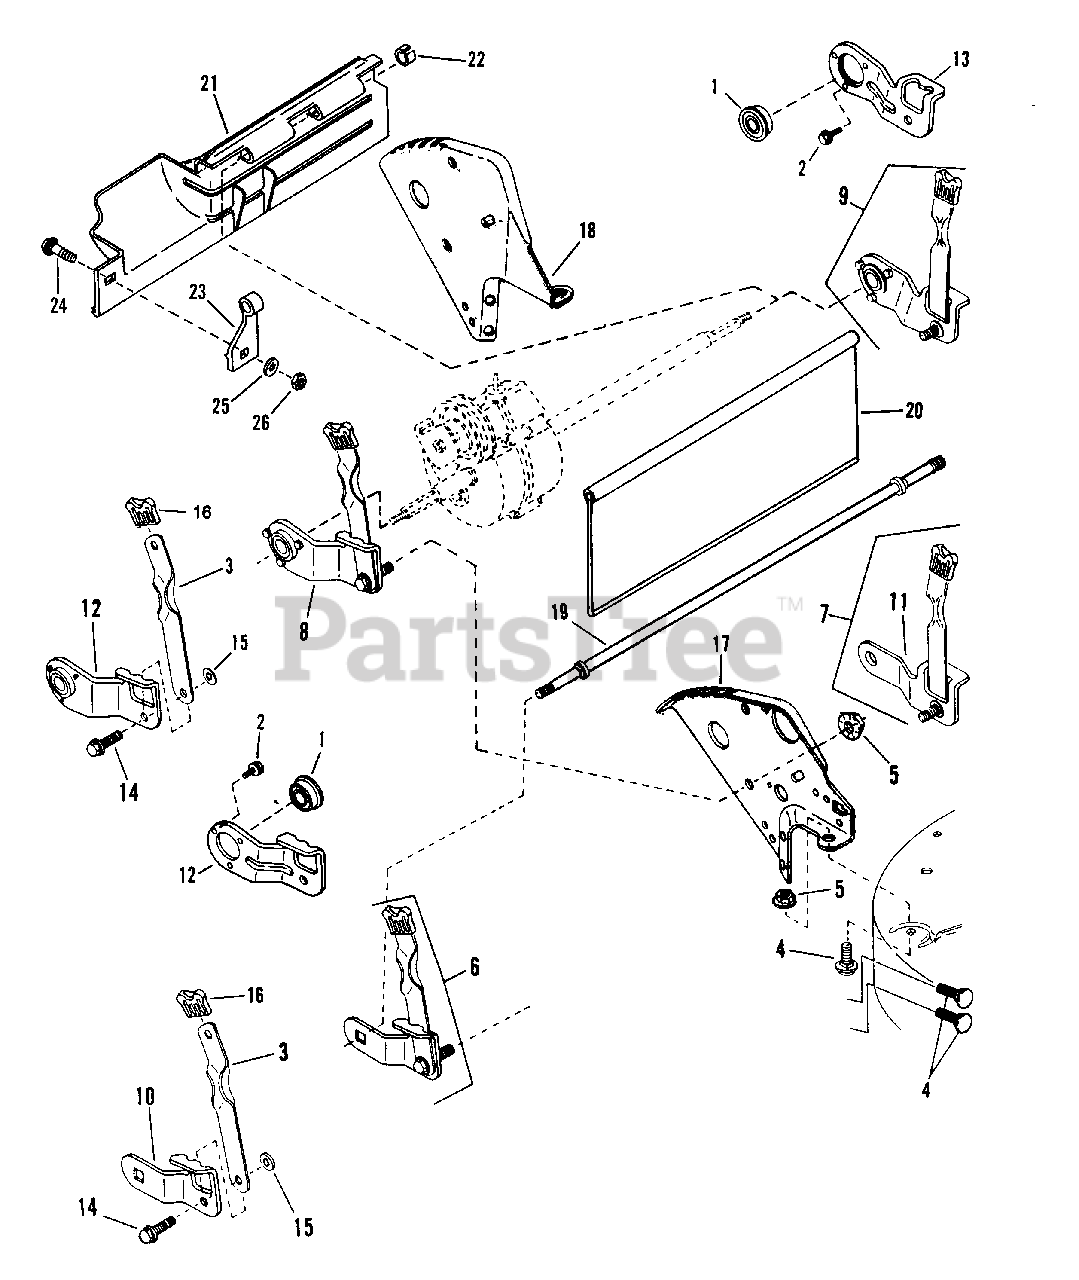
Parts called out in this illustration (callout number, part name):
1	BEARING, 9/16 (Heavy duty)
1	BEARING, 9/16
2	SCREW, #10-32 x 3/8" Self-Tapping (Torx)
3	LATCH, Height Adjusting (Long)
3	LATCH, Height Adjusting - Right (Long)
3	LATCH, Height Adjusting - Left (Long)
4	BOLT, 5/16-18 x 3/4" Short Neck Carriage, Grade 5
5	NUT, 5/16-18 Hex Flange Lock, Grade 5 (B)
6	ASSEMBLY, Wheel Arm (Round Hole, Right Rear) Push Models
7	ASSEMBLY, Wheel Arm (Square Hole, Left Rear) Push Models
8	ASSEMBLY, Wheel Arm (Right Rear)
9	ASSEMBLY, Wheel Arm (Left Rear)
10	ARM, Round Axle End (Right Rear) Push Models
11	ARM, Square Axle End (Left Rear) Push Models
12	ARM, Wheel Right Rear
13	ARM, Wheel Left Rear
14	BOLT, 5/16-18 x 3/4" Shoulder
14	BOLT, 5/16-18 x 1" Shoulder
15	RETAINER, 5/16 Bolt
16	GRIP, Latch
17	BRACKET, Right Rear Wheel
18	BRACKET, Left Rear Wheel
19	AXLE
20	GUARD, Rear Foot
21	GUARD, Rear Foot
22	RING
23	SUPPORT, Foot Guard
24	BOLT, 1/4-20 x 1/2" Short Neck Carriage, Grade 5
25	WASHER, 1/4 Internal Tooth Lock
26	NUT, 1/4-20 Hex, Grade 5
